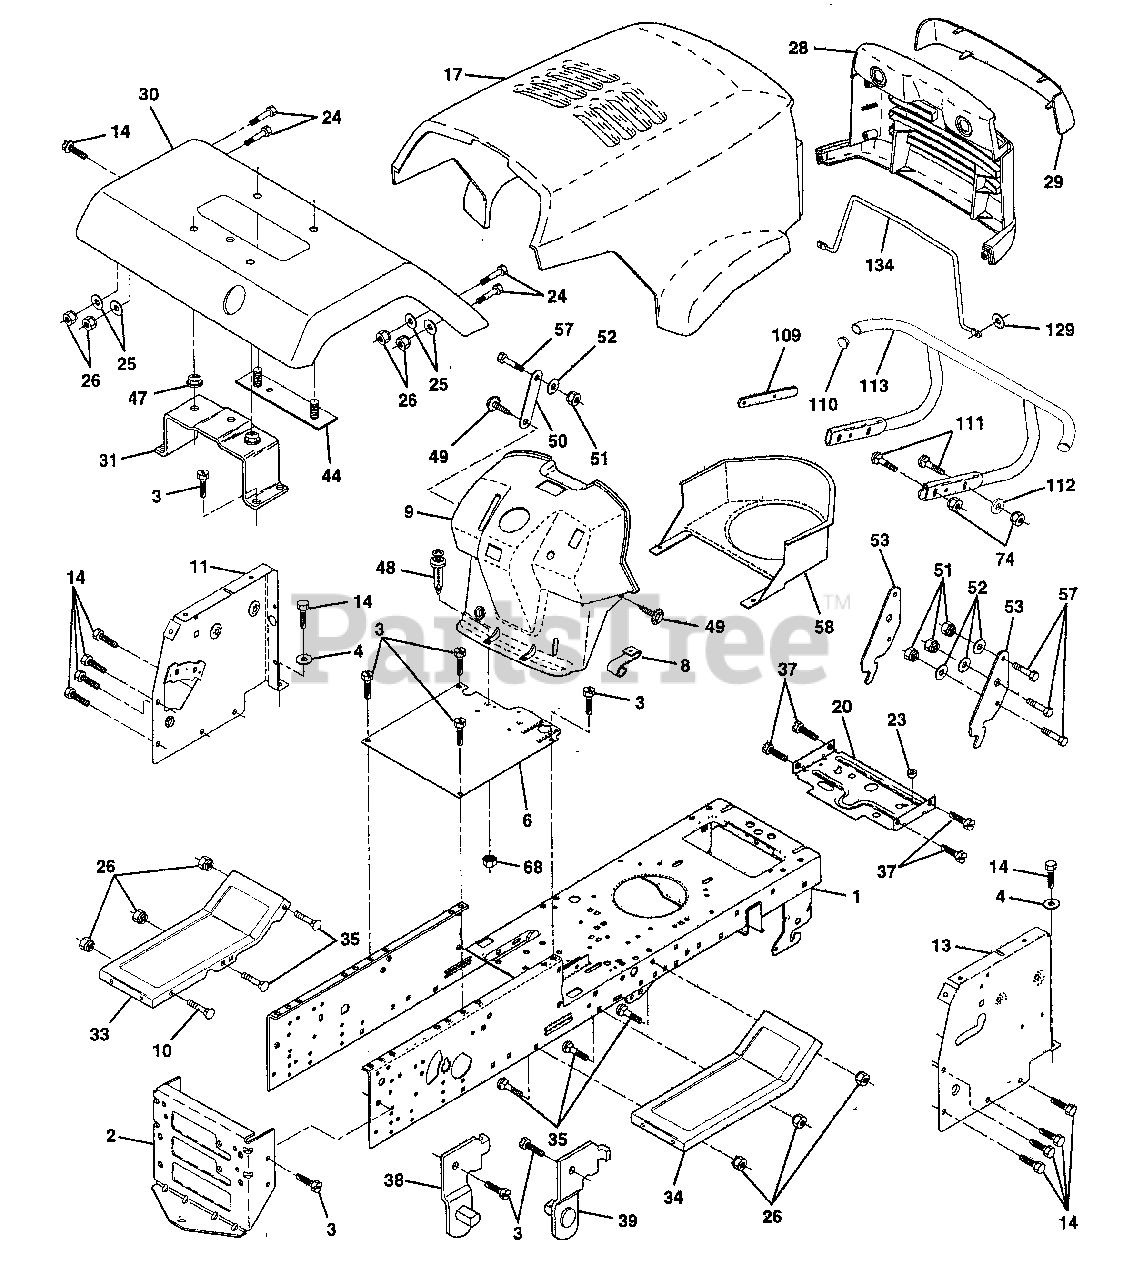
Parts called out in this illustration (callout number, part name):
1	Chassis Weldment 11 ga
2	Drawbar, Stretch
3	Screw Thdrol 3/8-16x3/4 Ty-tt
4	Washer 13/32 x 3/4 x 16 Ga.
6	Saddle LT Fender Shift
8	Clip Insulator.406 Mt Hole
9	Dash P/L w/amm w/HM w/PTO Grey
10	Bolt Carriage 3/8-16 x 1
11	Panel Pnt Dash Lh
13	Panel Dash Rh Asm
14	Screw Thdrol 3/8-16x1/2 Ty-ft
17	Hood LT/PL Husqvarna
20	Plate Mtg. Battery Fuel Tank. 95
24	Bolt Fin Hex 3/8-16unc X 1 Gr. 5
25	Washer 13/32 X 13/16 X 12 Ga
26	Nut Lock Hex W/Ins 3/8-16 Unc
28	Grille LT/PL Husqvrna
29	Lens LT/PL Husqvrna
30	Fender YT/GT w/Shift w/Fuel 94
31	Bracket Asm Fender
33	Footrest Pnt Lh LT/YT/GT 95
34	Footrest Pnt Rh LT/YT/GT 95
35	Bolt Rdhd Sht Sqnk 3/8-16 X3/4
37	Screw Thdrol 5/16-18 X1/2
38	Bracket, Asm. Pivot, L.H., Mower Rear
39	Bracket, Asm. Pivot, R.H., Mower Rear
44	Strap asm Fender
47	Nut, Push Nylon
48	Rivet Push Plate D Plastick Blk
49	Screw Hexwsh. Thdrol 1/4-20 x 3/4
51	Nut Lock Hex W/Ins 1/4-20
52	Washer 9/32 x 7/8 x 16 Ga.
53	Bracket Pnt. Pick off LT/PL Husq.
57	Bolt Hex 1/4-20 x 3/4
58	Air Duct CV18
68	Nut Keps Hex 1/4-20
74	Nut Crownlock 3/8-16 UNC
109	Bracket Extension Bumper
110	Plug Plastic
111	Bolt Carriage 3/8-16 x 1-1 /4
112	Washer 13/32 x 13/16 x 16 Ga.
113	Bumper Asm.
129	Washer 9/32 x 5/8 x 16 Ga.
134	Rod Support Hood- LT/PL Husq.
